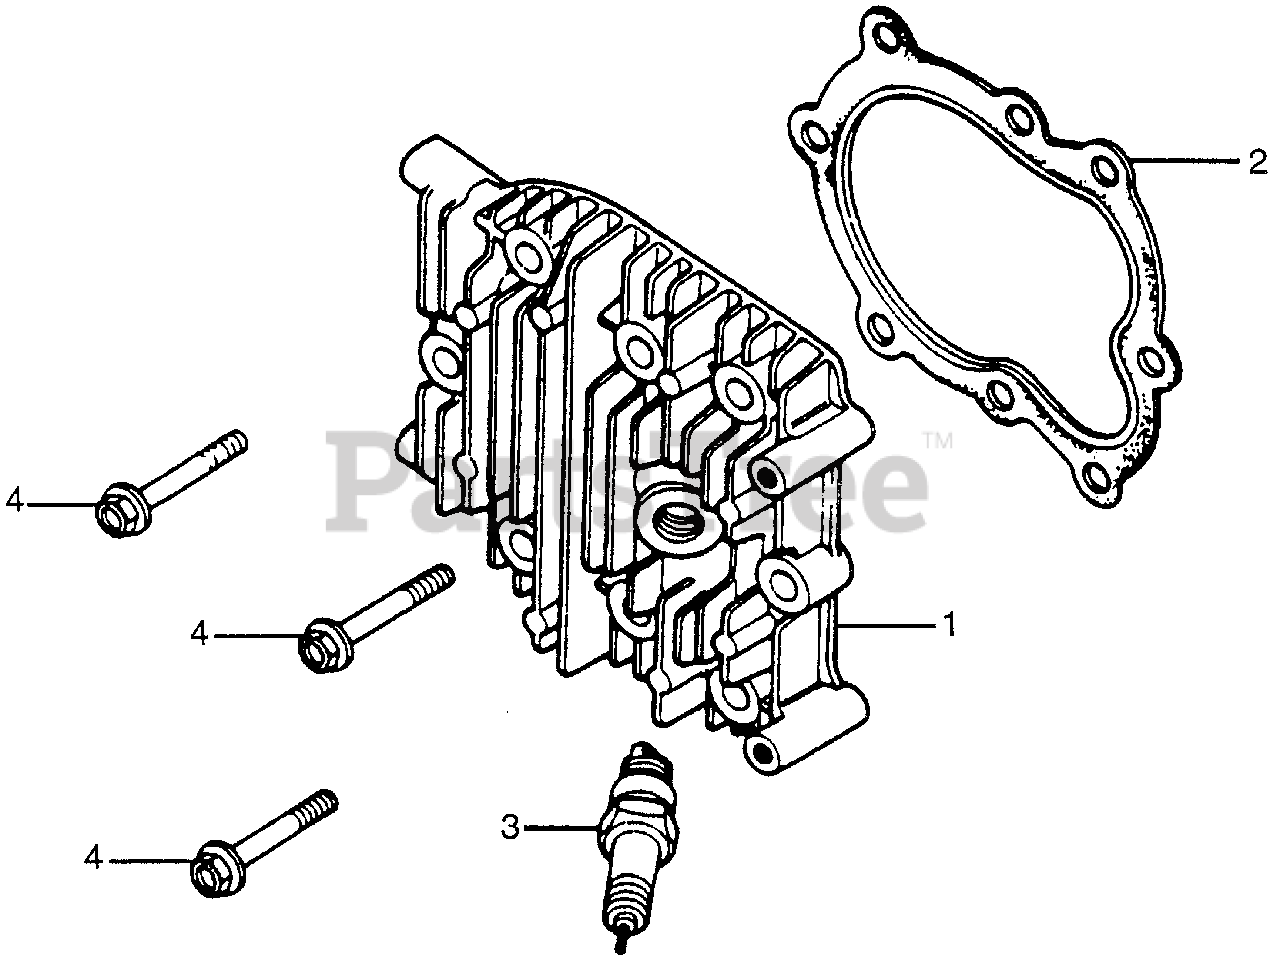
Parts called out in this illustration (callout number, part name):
1	CYLINDER HEAD
2	GASKET, CYLINDER HEAD
3	SPARK PLUG (BR6HS) (NGK)
4	BOLT, FLANGE (8X40)
